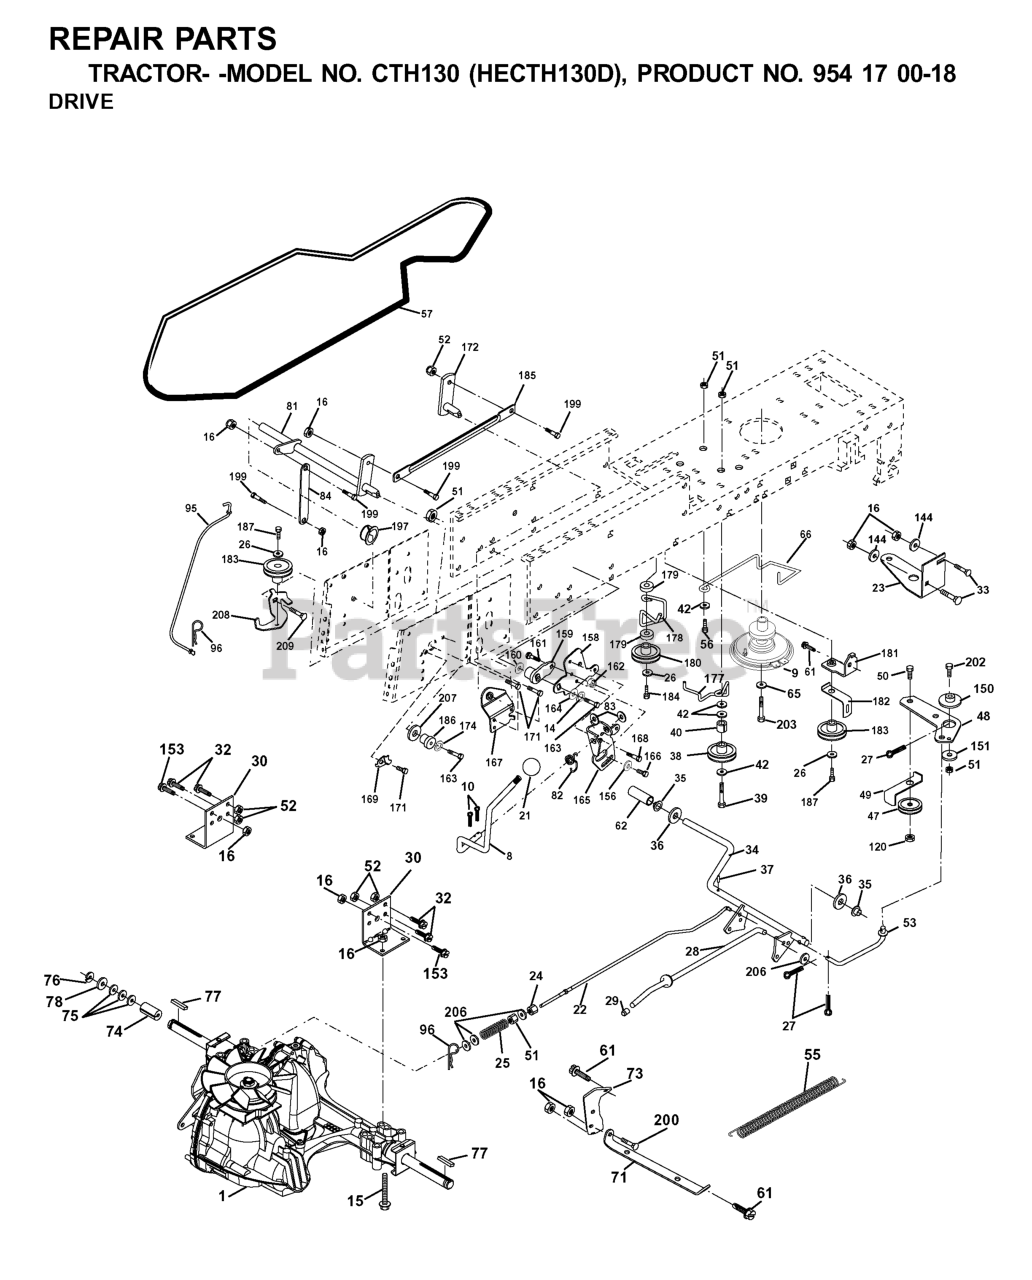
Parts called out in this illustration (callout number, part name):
8	ROD.SHIFT.FENDER.ADJ.LT.CRD
9	CLUTCH ASSY
10	PIN COTTER
14	LOCKWASHER
15	BOLT HEX 5/16-18 GR 5
16	NUT.71038.31-18.HEX.NYLOCK
21	KNOB.DUCKHEAD.1/2
23	Bracket Clutch Noram
24	NUT
25	SPRING ROD LT
26	WASHER
27	COTTER PIN
28	ROD BRAKE PARK LT
29	PLUNGER CAP
30	BRKT, TRNSXLE MNT 20"
32	BOLT
33	RP BOLT 5/16-18 X3/4 ZN/YEL GR
35	BEARING.NYLON
36	WASHER LT
37	DRIVE PIN
38	PULLEY.FLAT
42	WASHER
47	IDLER PULLEY
48	BELLCRANK, CLUTCH
49	RETAIN BELT
50	BOLT
52	LOCKNUT
53	LINK, CLUTCH LT
55	SPRING, RETURN LT
57	V-BELT 113"
61	SCREW 3/8-16X3/4
62	COVER, PEDAL (1 2)
65	LOCKWASHER
66	KEEPER BELT ENGINE
71	STRAP TORQUE LH HYDRO
73	STRAP TORQUE RH HYDRO
74	SPACER AXLE
77	SQUARE KEY
81	ASM.CROSS.SHAFT.REAR.CRD.0510
82	SPRING,TORSION
83	WASHER
84	LINK.PNT.TRANSAXLE.0510.CRD
95	LINK
96	RETAINER M
120	NUT LOCK FLG 3/8-16 UNC
144	Washer 11/32 x 5/8 x 16 Ga SD
150	BUSHING.BELLCRANK.GRD.DR
151	WASHER 12/32X2X10GA
153	BOLT RB
156	WASHER.SRRTD.5/16
158	BRACKET
159	HUB
160	Washer 29/32 x 1 - 1/4 x 16 Ga.
161	BOLT
162	NUT.CROWNLOCK.1/4
163	BOLT
164	Washer 5/8 x .281 x 10 Ga.
165	RP BRACKET
167	BRACKET.SUPT.SHIFT.CRD
168	BOLT.SHOULDER.5/16-18X
169	PLATE.FASTENING.CROSS.SHAFT
171	SCREW LT
172	LINK
174	LOCKWASHER
180	PULLEY.FLAT.IDLER
181	BRKT.IDLER.GRD.DR.CRD
182	KEEPER BELT
183	PULLEY.V-IDLER
184	SCREW.HXWSH.3/8
185	LINK
186	HUB.TAPERED.ROUND.CRD
187	SCREW.3/8-16
197	NYLINER SNAP 5/8" ID
199	BOLT SHOULDER 5/16-18 UNC
200	BOLT
202	BOLT.3/8-16X1.50
203	BOLT.HEX.7/16-20 X 5
206	WASHER
207	WASHER NYL
209	BOLT
